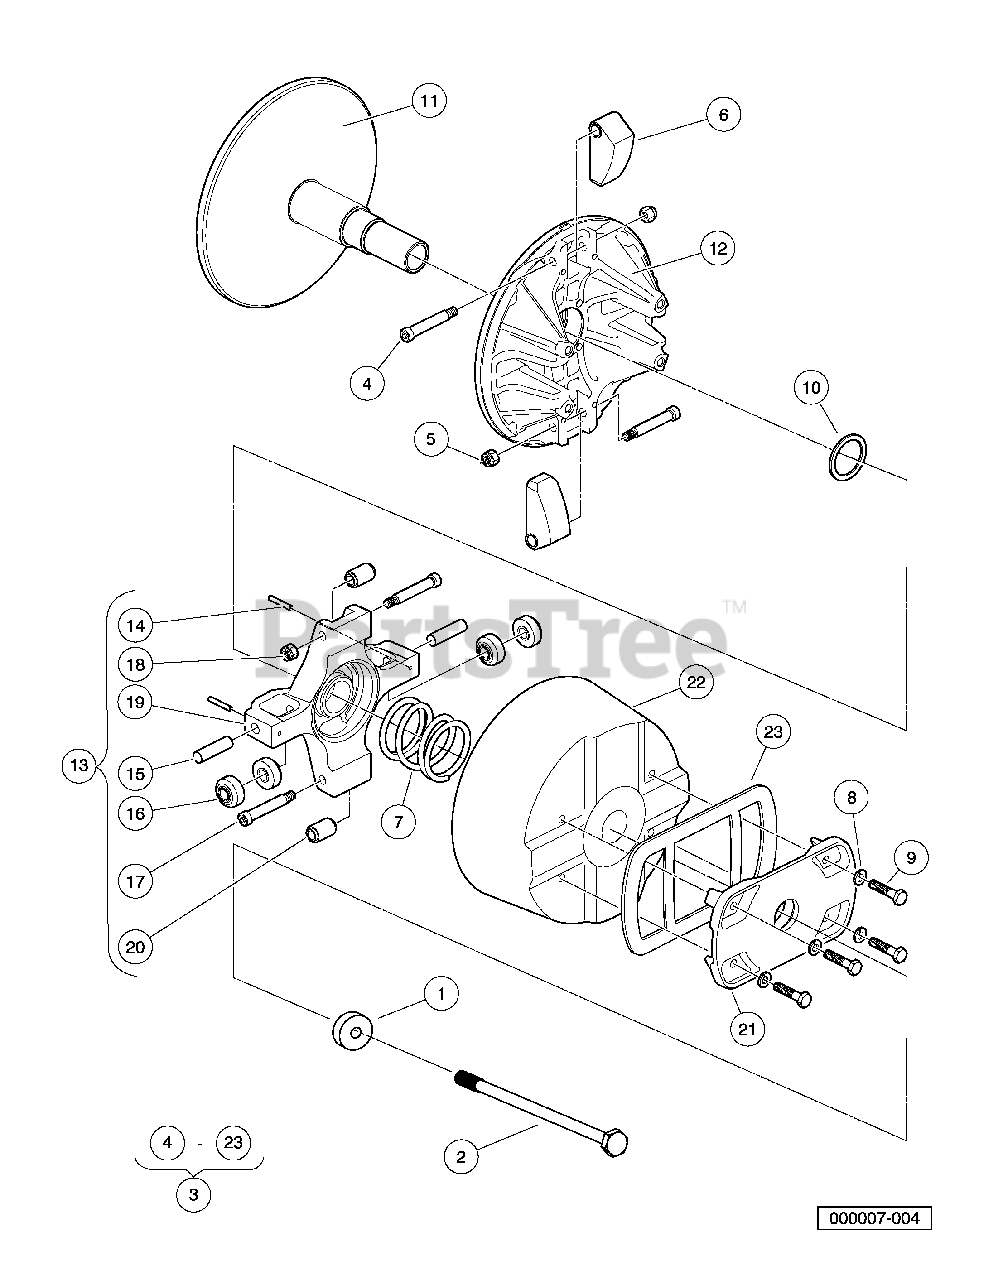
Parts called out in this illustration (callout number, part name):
1	Washer, Stepped
2	Bolt, M10 X 1.5 X 160
3	Clutch, 4x4, Diesel, W/cover
4	Screw, Shlder Hex, .312 X 1.75
5	Nut, Lock Hex, 1/14-20, Flexlc
6	Sub Assy, Wt Clutch, Diesel
7	Spring, Compression, Primary
8	Washer, Lock, H-Spring, 1/4
9	Screw, Cap, Hex Hd, 1/4 X 1.25
10	Shim, 1.63 X 1.33
11	Subassembly, Drive Clutch
12	Subassembly, Moveable, Drive Clutch
13	Subassembly, Spider Utility, Diesel
14	Pin, Spring Slotted,1.25 X 1.0
15	Pin, Dowel, .375 X 1.50
16	Roller, Torque, Diesel
17	Screw, Shlder Hex, .312 X 1.75
18	Nut, Lock Hex, 1/14-20, Flexlc
19	Spider, Drive Clutch
20	Sub Assy, Roller Weight
21	Cover, Drive Clutch
22	Cover, Clutch, 4x4
23	Gasket, Cover, Clutch, 4x4
